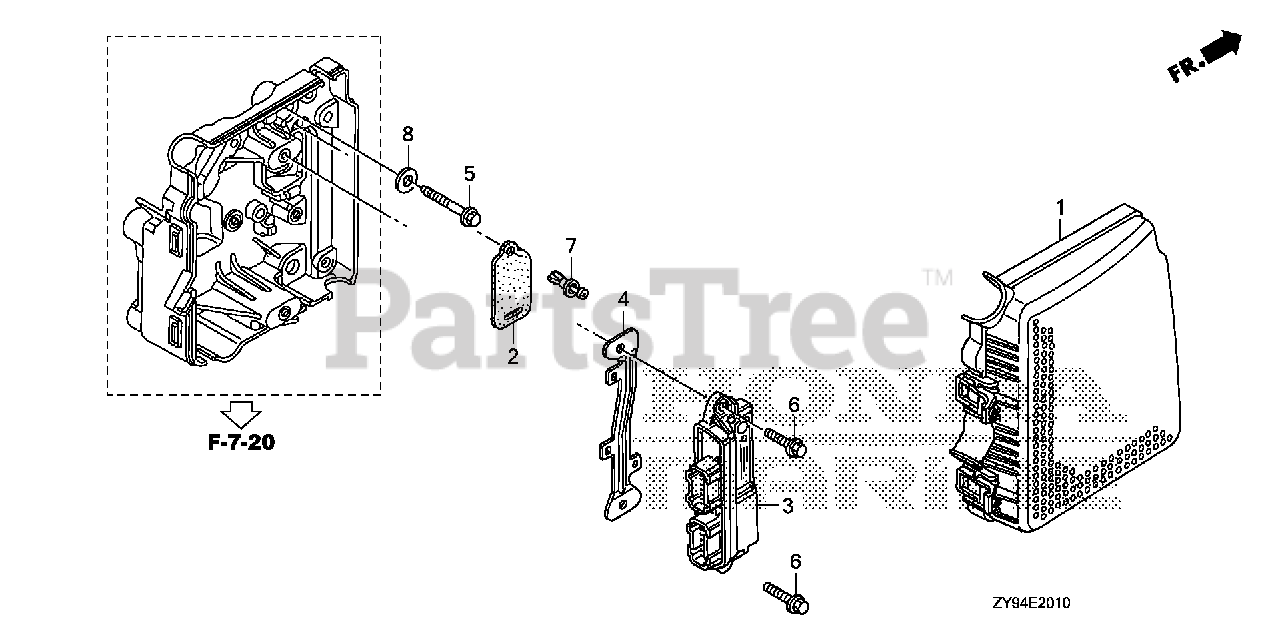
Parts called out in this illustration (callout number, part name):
1	COVER, ELECTRONIC PARTS
2	RUBBER, GROUND TERMINAL
3	CONTROL UNIT, ELECTRONIC
4	BRACKET, ELECTRONIC CONTROL UNIT
5	BOLT, FLANGE (6X28) (CT200)
6	BOLT, FLANGE (6X20)
7	SCREW, RIVET (5X10)
8	WASHER, PLAIN (22X6X1.6)
